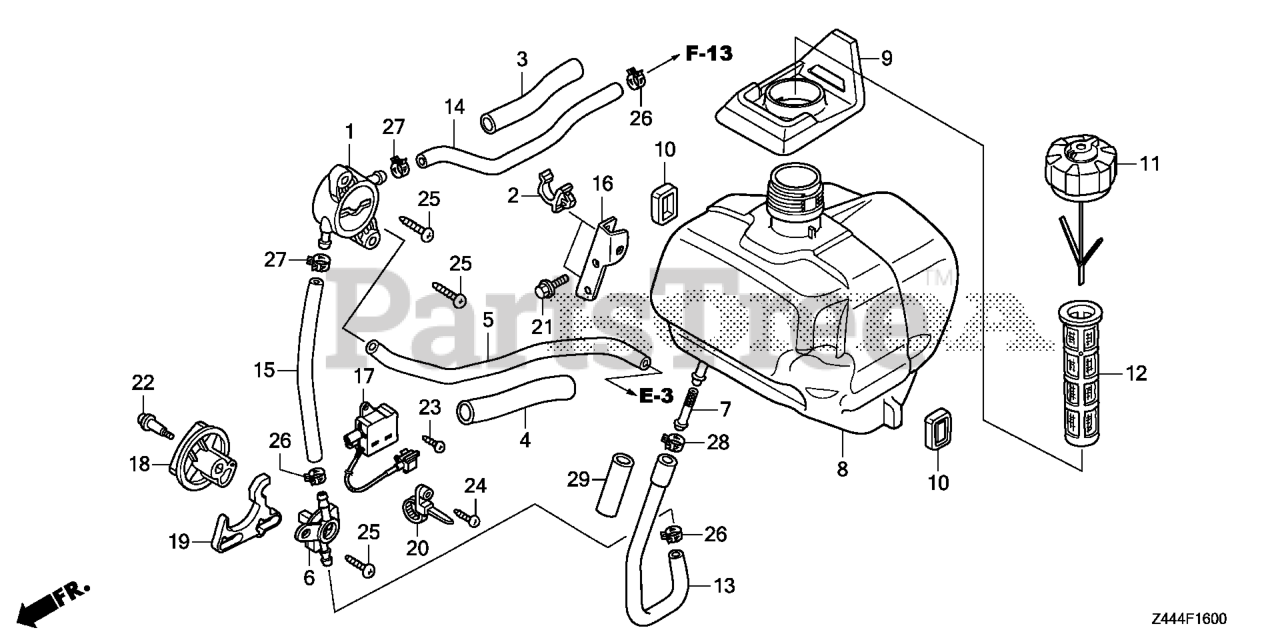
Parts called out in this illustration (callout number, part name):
1	PUMP ASSY., FUEL (MSDS)
2	CLIP, TUBE
3	RUBBER A, SUPPORTER
4	RUBBER B, SUPPORTER
5	TUBE, DIAPHRAGM
6	PETCOCK ASSY.
7	FILTER, FUEL
8	TANK, FUEL
9	SEAL, FUEL FILLER NECK
10	RUBBER A, TANK MOUNTING
11	CAP ASSY., FUEL TANK
12	FILTER, FUEL
13	TUBE, FUEL TANK (FKM)
13	TUBE, FUEL TANK
14	TUBE A, FUEL (FKM)
14	TUBE, A FUEL
15	TUBE B, FUEL (FKM)
16	BRACKET, FUEL TUBE
17	SWITCH ASSY., ENGINE STOP
18	KNOB, ENGINE SWITCH
19	PLATE, ENGINE SWITCH
20	BAND, HARNESS
21	BOLT, FLANGE (6X12) (CT200)
22	SCREW, PAN (4X19)
23	SCREW, TAPPING (3X12)
24	SCREW, TAPPING (3X16)
25	SCREW, TAPPING (5X20) (PO)
26	CLIP, TUBE (D8)
27	CLIP, TUBE (D8.5)
28	CLIP, TUBE (10.5MM)
29	RUBBER, SUPPORTER (C)
